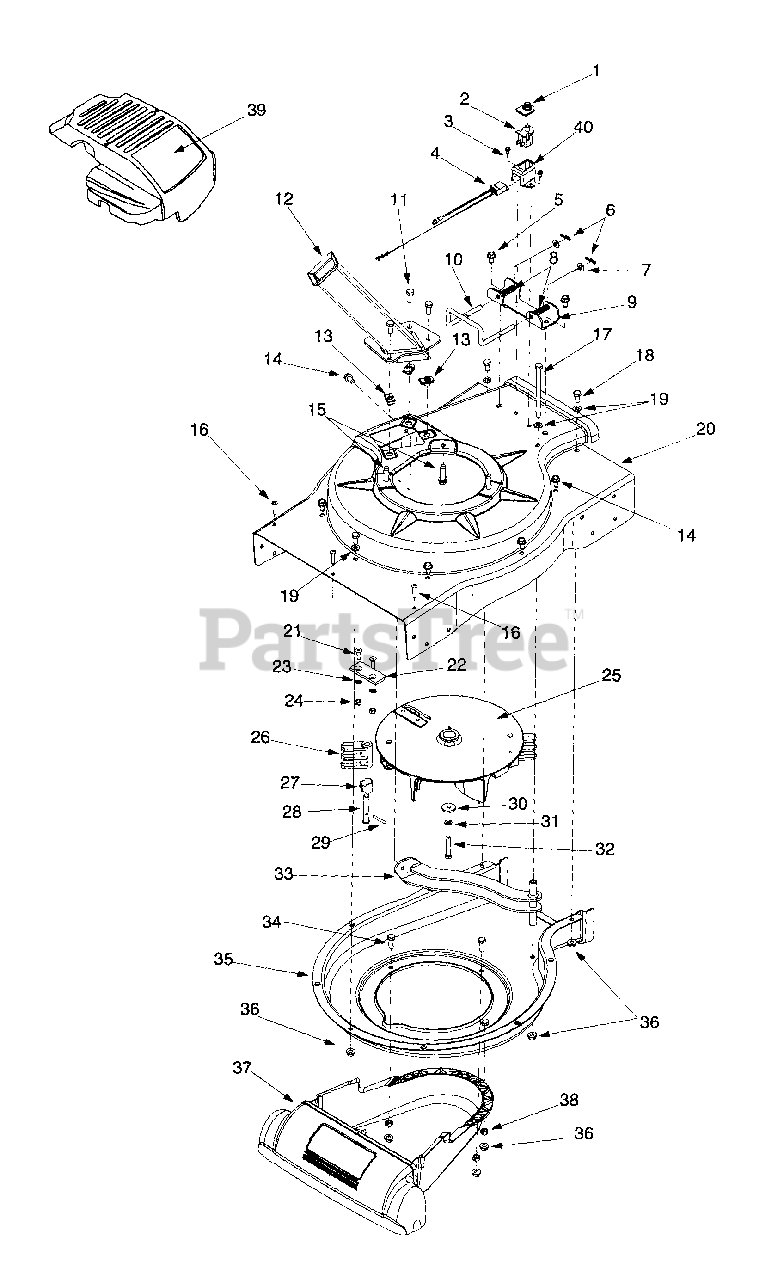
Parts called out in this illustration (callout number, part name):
1	Switch Cover
2	Safety Switch
3	Hex Washer Screw #10-16 x .50
4	Wire Harness
5	Hex Washer Screw 5/16-18 x .625
6	Cotter Pin
7	Flat Washer .330 ID x .630 OD
8	Compression Spring
10	Lock Rod
11	Hex Cap Screw 5/16-18 x .75
13	U-Clip Lock Nut 5/16-18
14	Hex Washer Screw 5/16-18 x .625
15	Hex Washer Screw 3/8-16 x 1.25
16	Screw #12-16 x 1.0
17	Hex Cap Screw 5/16-18 x 4.5
18	Hex Cap Screw 5/16-18 x .625
19	Flat Washer .330 ID x .630 OD
22	Chipper Blade
23	Lock Washer 5/16
24	Hex Lock Nut 5/16-24
25	Impeller Ass'y
26	Flail Blade
27	Pin Clip
28	Clevis Pin
29	Spiral Pin
30	Flat Washer 3/8 ID x 1.25 OD
31	Lock Washer 3/8
32	Hex Cap Screw 3/8-24 x 2.0
34	Hex Cap Screw 5/16-18 x .875
36	Lock Nut 5/16-18
37	Nozzle Cover
38	Lock Nut 5/16-18
39	Shroud
40	Safety Switch Cover
